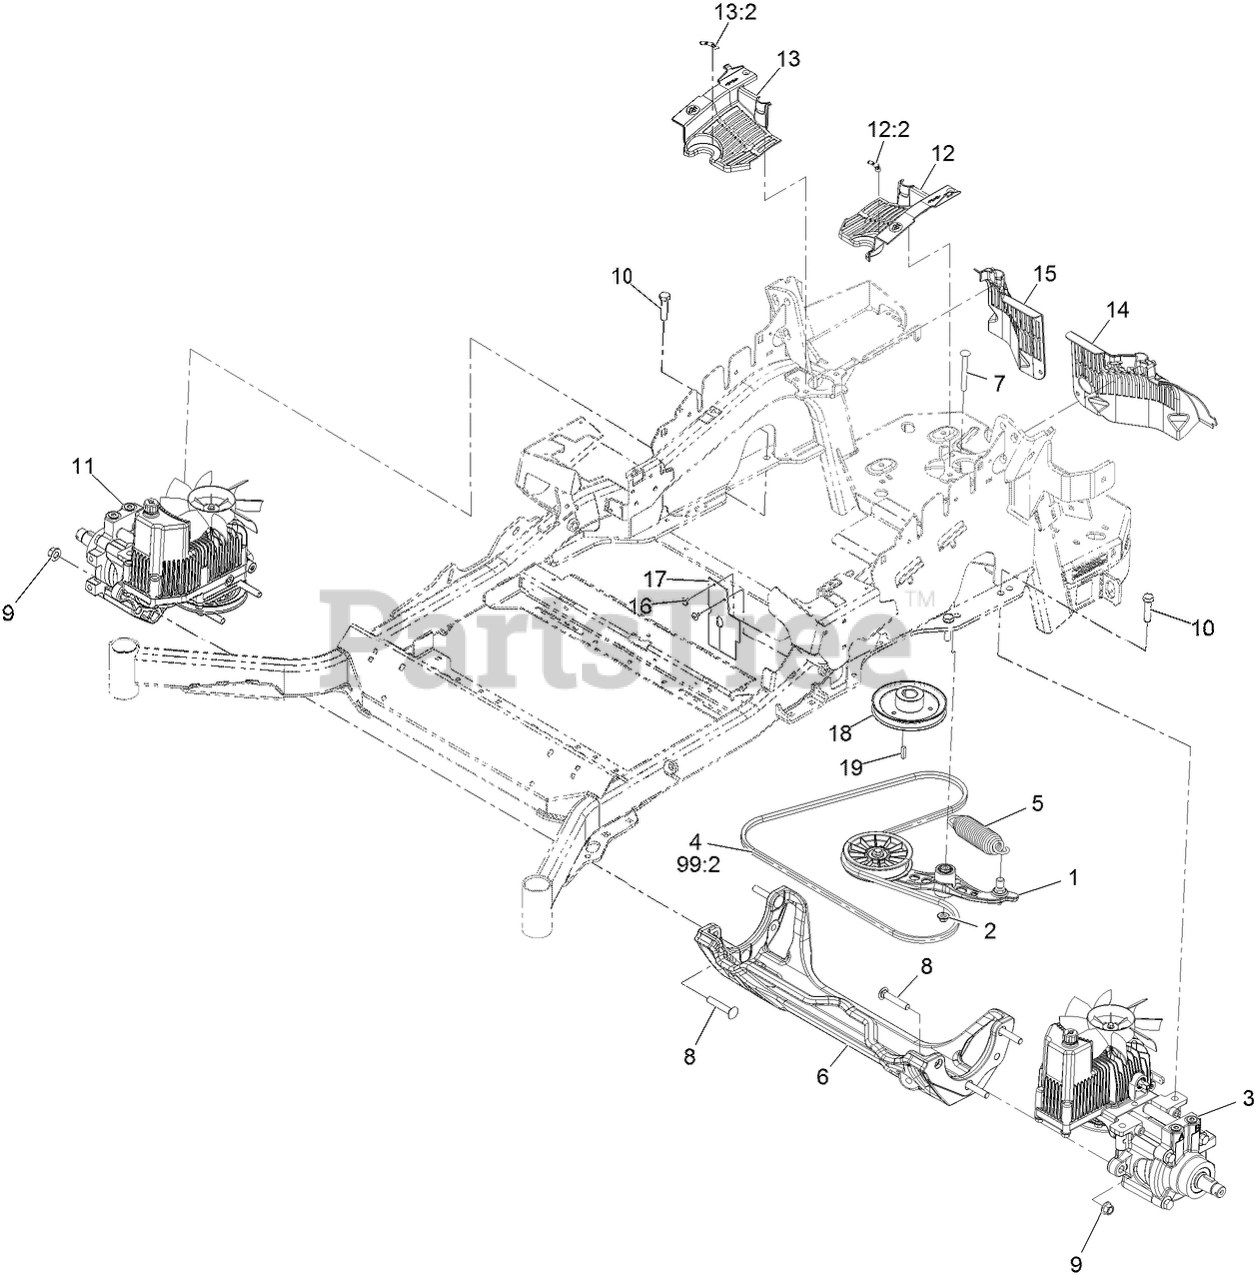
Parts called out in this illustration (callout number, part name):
1	PUMP IDLER ASM
2	Nut-Nyloc 3/8-16 Flg
3	LH HYDRO ASM (16CC W/ SHO
5	SPRING-EXTENSION
6	CRADLE-HYDRO
7	BOLT-SHOULDER, CARRIAGE 3/8-16 X 3 1/2
8	SCREW-CARR
9	Nut-Lock 1/2-13
10	SCREW-HH
11	RH HYDRO ASM (16CC W/ SHO
12	LH HYDRO GUARD ASM
12:2	DECAL-OIL, HYDRO
13	RH HYDRO GUARD ASM
13:2	DECAL-OIL, HYDRO
14	GUARD-HYDRO, REAR (LH)
15	GUARD-HYDRO, REAR (RH)
16	RIVET-POP
17	DEFLECTOR-AIR FLOW
18	SHEAVE
99:2	BELT
